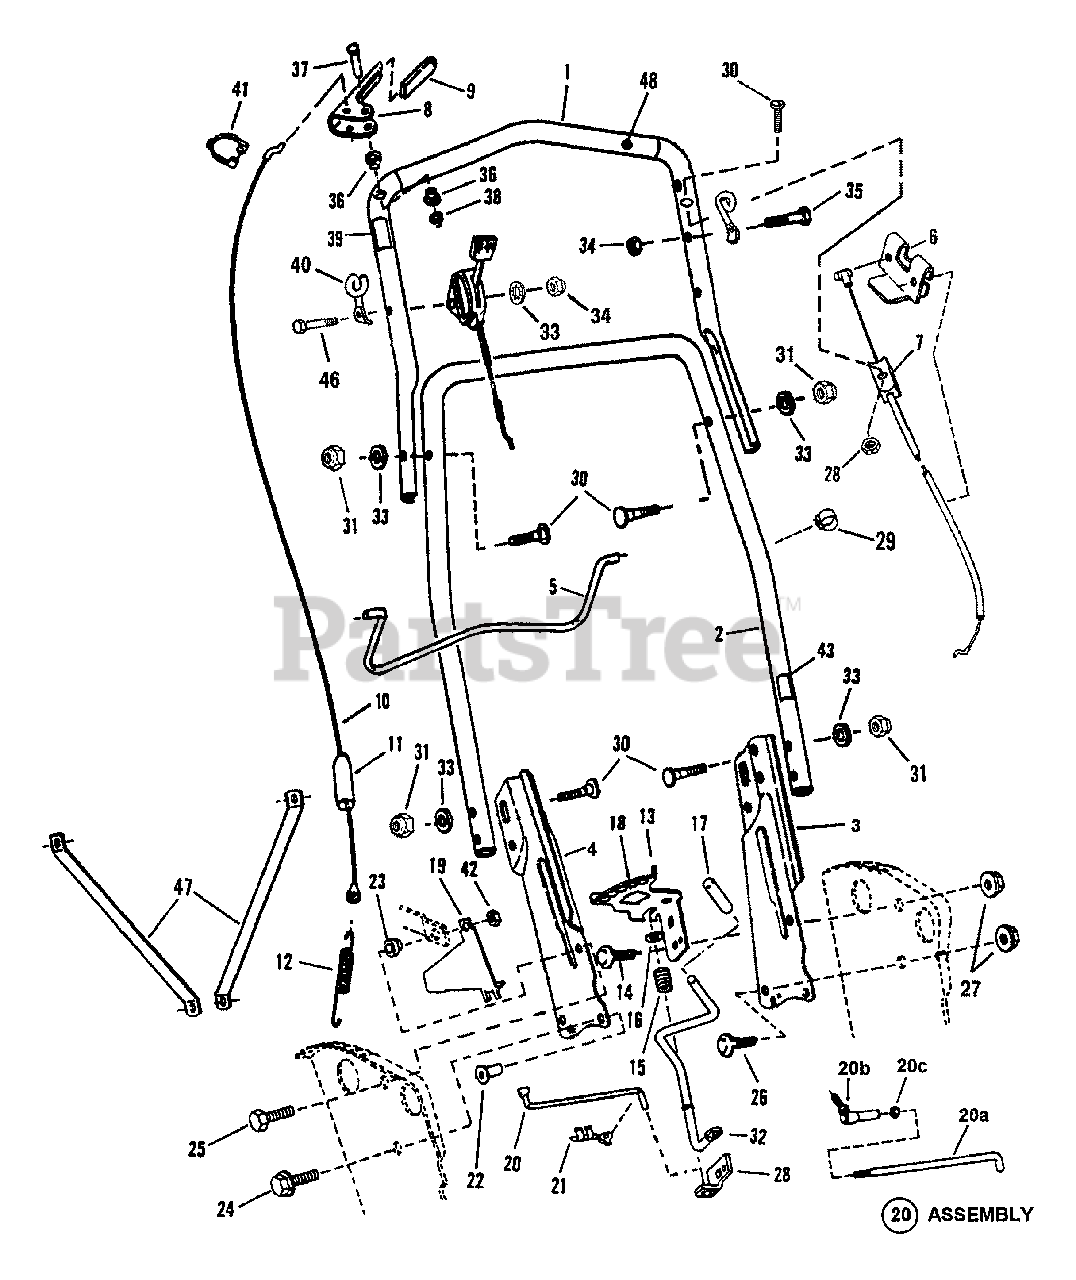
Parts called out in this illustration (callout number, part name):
1	HANDLE, Upper
2	HANDLE, Middle
3	HANDLE, Lower Left Hand
4	HANDLE, Lower R.H. Adjustable
5	BAIL, OPC Control (12.5" Wide)
6	CLIP, Blade Control
7	CABLE, Blade Control
8	HANDLE, Wheel Drive
9	GRIP, Wheel Drive Handle
10	CABLE, Clutch Pull (Z-Bend, 38-5/16" Long)
11	COVER, Vinyl
12	SPRING, Clutch
13	SECTOR, Speed
14	BOLT, 5/16 x 1" Round Head Carriage, Grade 5
15	SPRING, Speed Control
16	WASHER, 3/8" Flat
17	GRIP, Speed Control Handle
18	DECAL, Speed Select
19	GUIDE, Lower V-Belt
20	ASSEMBLY, Transfer Rod
20A	LINK, Transfer
20B	BALL JOINT, 1/4-28
20C	NUT, 1/4-28 Hex
21	CLIP, Transfer Rod
22	TEE-NUT, 5/16-18
23	BUSHING, Differential
24	BOLT, 5/16-18 x 3/4" Flange Lock, Grade 5
25	SCREW, 5/16-24 x 1" Hex Cap, Grade 5
26	BOLT, 5/16-18 x 5/8" Short Neck Carriage, Grade 5
27	NUT, 5/16-18 Hex Flange Lock, Grade 5
28	BRACKET, Speed Control Rod
29	TIE, Wire
30	SCREW, 5/16-18 x 1-1/2 Curved Head, Grade 2
31	NUT, 5/16-18 Hex
32	LEVER, Speed Control
33	WASHER, 5/16 Internal Tooth Lock
34	NUT, 1/4-20 Hex
35	SCREW, 1/4-20 x 2" Hex Cap, Grade 5
36	BUSHING
37	PIN, Clutch Handle
38	PUSH-NUT, 1/4"
39	DECAL, Blade Control (Right Hand Side)
40	GUIDE, Rope
41	CLAMP
42	NUT, 5/16-24 Hex Center Lock, Grade 5
43	DECAL, Shift Warning
46	SCREW, 1/4-20 x 1-3/4 Hex Cap, Grade 5
47	BRACE
48	FOAM GRIP
